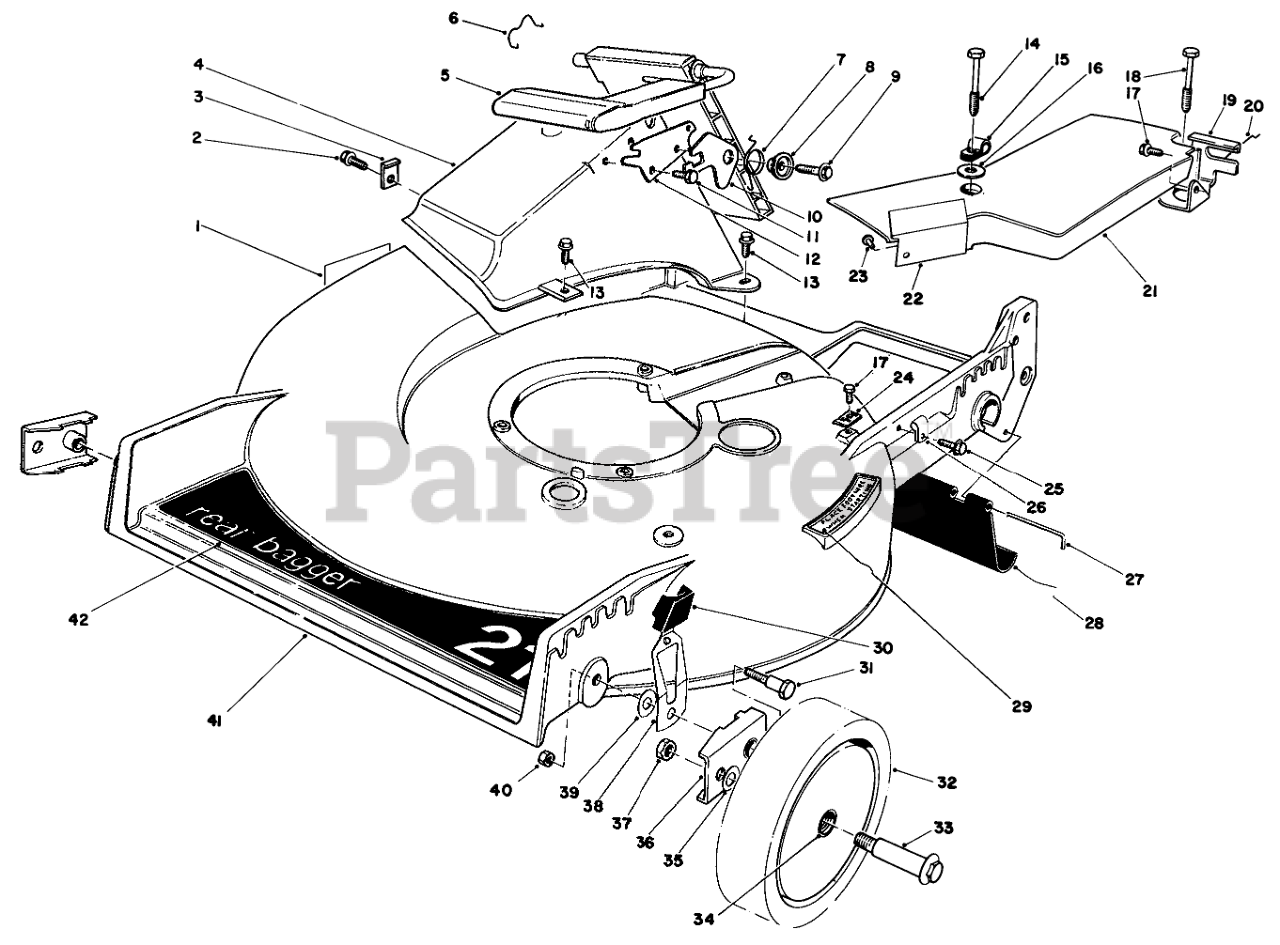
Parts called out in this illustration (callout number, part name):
1	DECAL-DANGER
2	SCREW
3	TUNNEL CLIP
4	Tunnel Discharge
5	Discharge Door Assembly
6	DOOR RET SPRING
7	TORSION SPRING
8	DOOR SPACER
9	SCREW-HWH
10	SAFETY LATCH
11	SCREW-PLASTITE
12	DOOR LATCH PLATE
13	SCREW-HWH
14	SCREW-SPECIAL
15	CLAMP-CABLE
16	WASHER
17	SCREW-HWHTF
18	SCREW-HHFTF
19	Bracket-Traction Adj.
20	RETAINER-CABLE
21	Belt Cover Assembly (Incl. Ref. #22 & 23)
22	HEAT SHIELD
23	RIVET-HEAD, FLAT
24	Cable Clamp
25	SCREW
26	CLAMP-CABLE
27	ROD-SHIELD
28	SHIELD-TRAILING
29	STEP PAD DECAL
30	KNOB-ARM
31	PIVOT SCREW
32	Wheel & Tire Assembly (Incl. Ref. #34)
33	WHEEL BOLT
34	BUSHING
35	WASHER
36	HP PIVOT ARM ASM
38	Spring Arm
39	Washer
40	NUT-LOCK, NI
41	Housing
42	DECK DECAL
